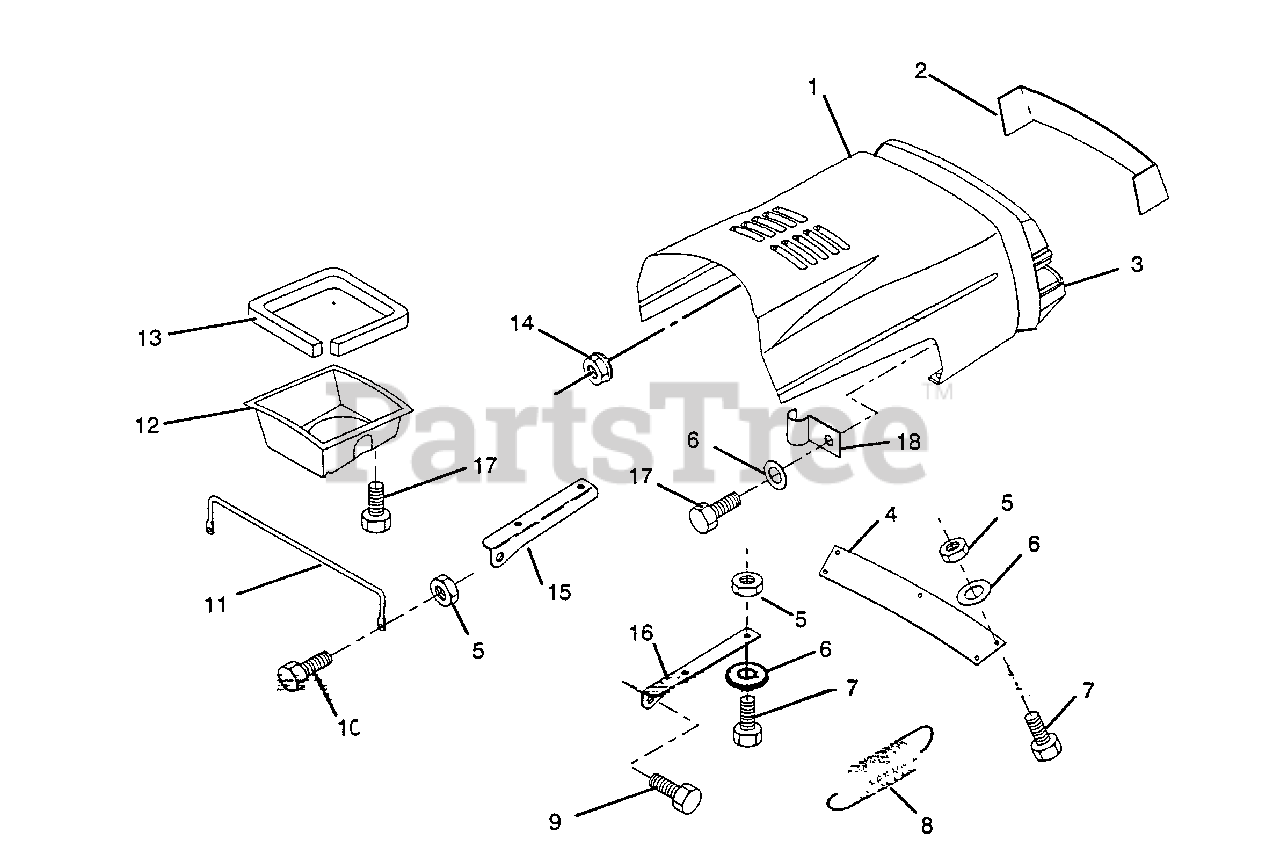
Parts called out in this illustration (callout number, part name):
1	Hood
2	Lens, Plate, Grill
3	Grill
4	Strap, Grill
5	Nut, Hex, Keps 1/4-20
6	Washer, 9/32 x 5/8 x 16 Ga.
7	Bolt, Hex Fin. 1/4 - 20 UNC 5/8 Gr. 5
8	Extension, Spring
9	Bolt, Shoulder
10	Bolt, Hex Fin. 1/4-20 x 5/8 Gr. 5
11	Brace, Hood
13	Strip, Foam
14	Nut, Self-Thd wsh-hd. 3/16
15	Bracket, Hood L.H.
16	Bracket, Hood R.H.
17	Screw, Fin. Hex #13-16 Hi-Lo x 5/8
18	Clip, Fuel Line
